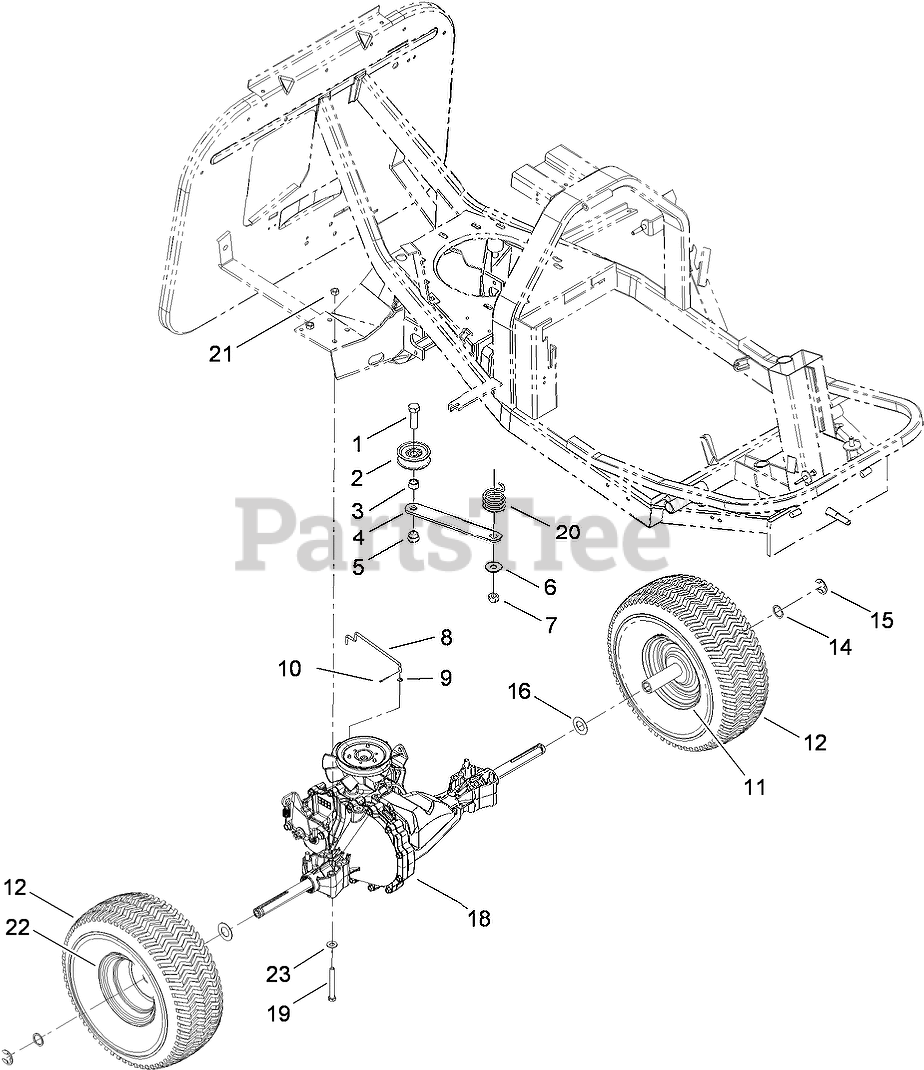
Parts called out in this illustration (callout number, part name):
1	Screw-HH
2	PULLEY
3	Spacer-Idler
4	Bracket
5	NUT-LOCK
6	Washer-Flat
7	NUT-LOCK, NI
8	LEVER-RELEASE
9	Washer-Flat
10	Pin-Hair
11	WHEEL-REAR, LEFT
14	SPACER-OUTER
15	RING-RETAINING, EXT
16	SPACER-INNER
18	TRANSAXLE ASM
19	Screw-HH
20	Spring-Extension
21	NUT-LOCK
22	WHEEL-REAR, RIGHT
23	WASHER-PLAIN
